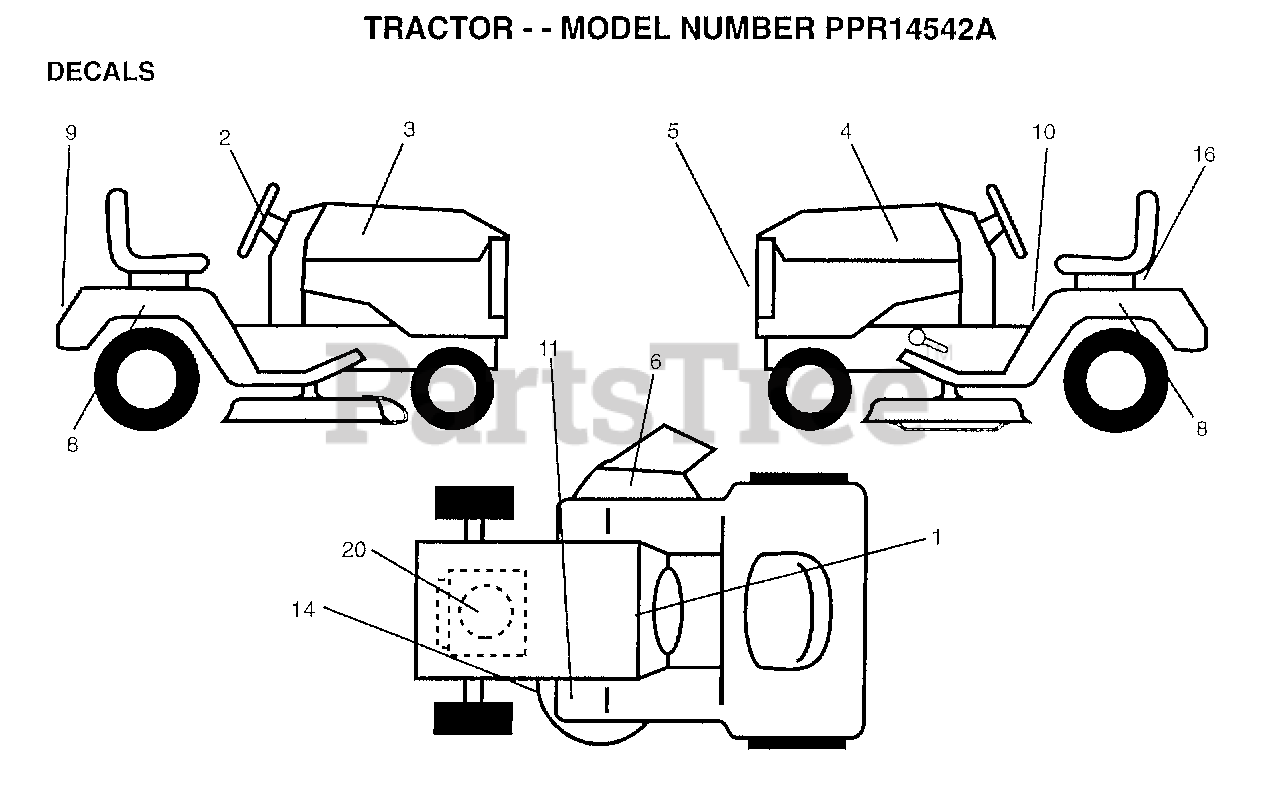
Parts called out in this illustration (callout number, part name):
1	"DECAL.OPER,SDL"
2	"DECAL WHEEL,STEER"
3	"DECAL-HOOD,RH"
4	"DECAL-HOOD,LH"
5	DECAL.GRILLE/LENS
6	"DECAL, WARNING"
8	DECAL.FENDER.SD.LAWN
9	"DECAL FENDER,LOGO"
10	DECAL.CAUT.ENG/FR
11	DECAL T
14	"DECAL-SCHEM,BELT"
16	DECAL.BATRY.3-3908
20	DECAL.ENGINE
